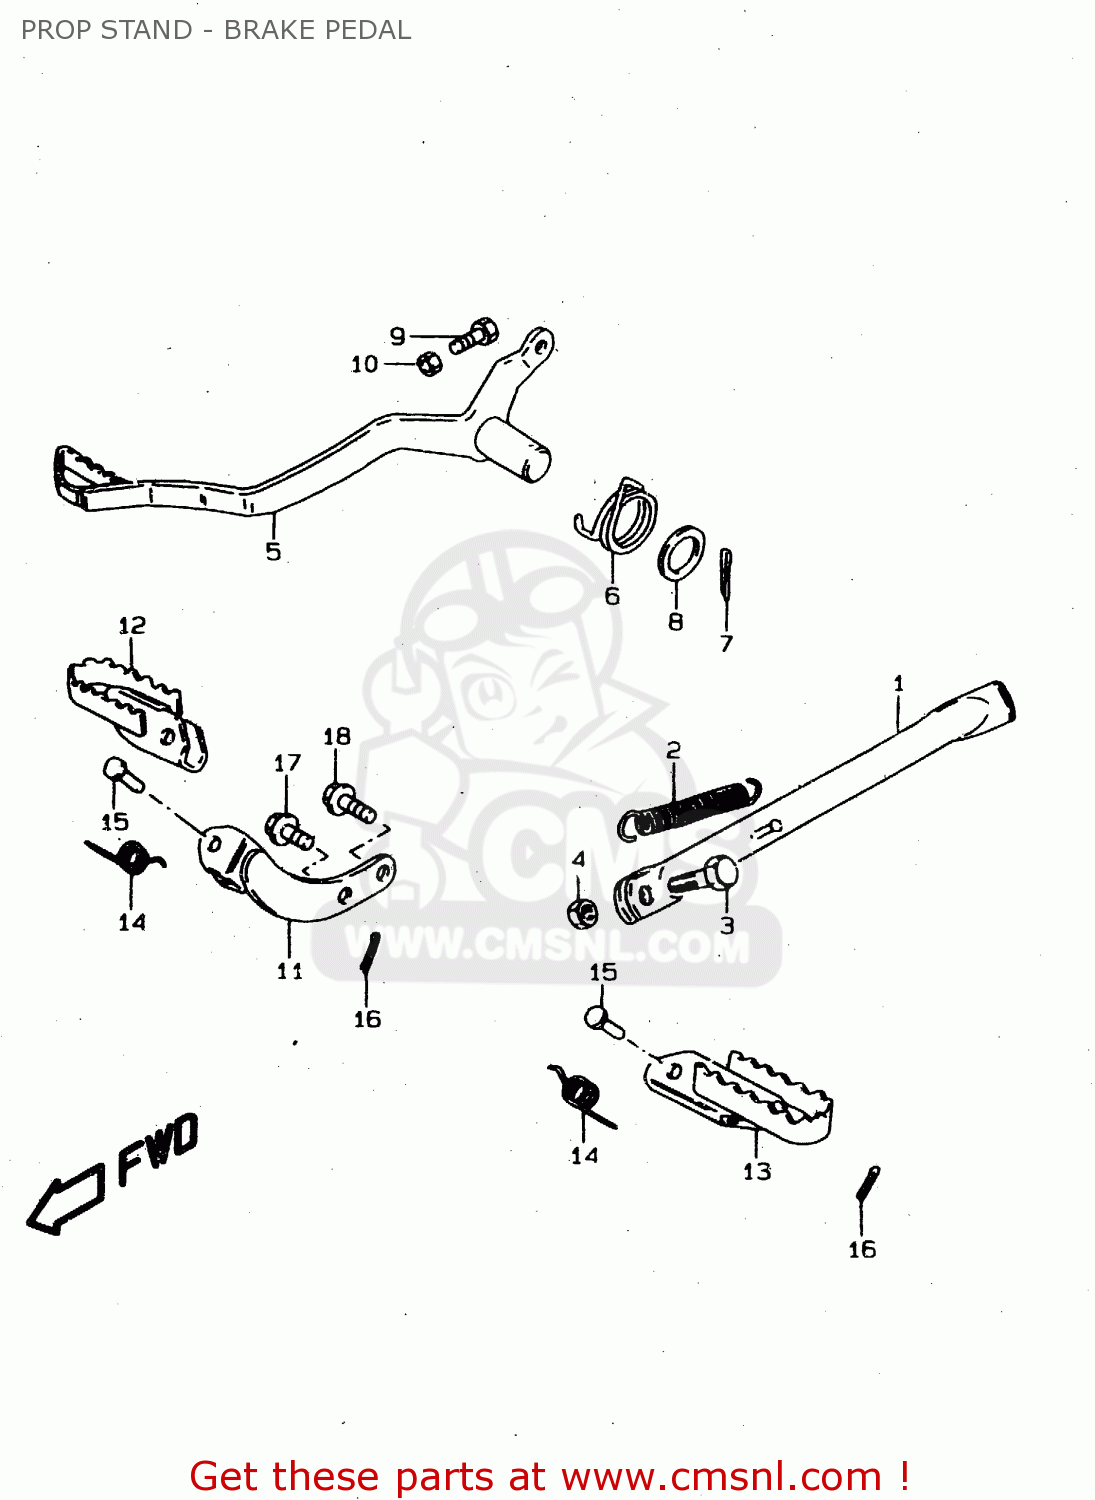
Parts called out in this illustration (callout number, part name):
1	STAND,SIDE
2	SPRING
3	BOLT(10X27)
4	NUT
5	PEDAL,BRAKE
6	SPRING
7	COTTER PIN
8	WASHER(15.5X26X2.3)
9	BOLT(6X23)
10	NUT 6MM
11	BAR,FRONT FOOTREST
12	FOOTREST,FR,R
13	FOOTREST,FR,L
14	SPRING
15	PIN
16	PIN
17	BOLT
18	BOLT(8X20)
